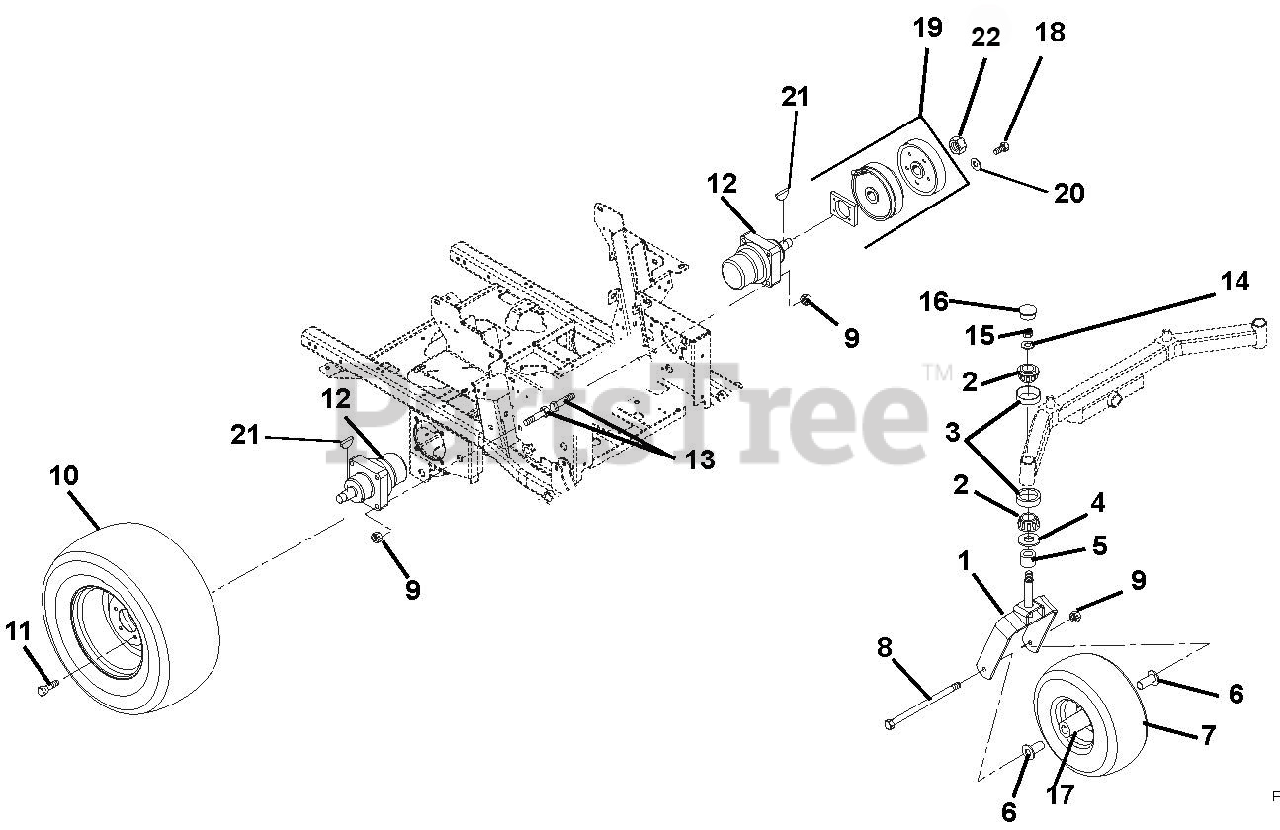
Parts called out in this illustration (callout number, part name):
1	FORK - FRONT
2	BRG, CONE W/ GREASE
3	BRG-CUP1.980X.420
4	BEARING SEAL 1.5 X 2 X .18
5	SPACER 1.005X1.5075X.375
6	SPACER, FRONT WHEEL
7	TIRE/WHEEL ASSY, 15X6.00-6
7	TIRE, 15X6.00-6
8	@BLT-HEX .50-13X9.00 GR5 YWZC
9	@NUT-LK-TOP-FLG .50-13 YWZC
10	TIRE/WHEEL ASSY, 24X11.50-12
10	TIRE, 24X11.50-12
10	TIRE/WHEEL ASSY, 23X10.00-12
10	TIRE, 23X10.00-12
11	BLT-LUG .50-20X1.38 YWZC
12	WHEEL MOTOR, 18E (CCW)
12	MOTOR, WHEEL HGM 15E (CCW)
13	BLT-HEX .50-13X2.75 YZ GR8
14	@WSHR-FL-STL.812X1.50X.135YWZC
15	NUT-JAM CTRLK .75-16 YWZC
16	CAP, DUST
17	BRG, 25MM ID X 52MM OD X 15MM
18	BLT-HEX .31-18X1.50 GR8YZ EP30
19	KIT, BRAKE SERVICE (1-SIDE)
20	@WSHR-LK .31X.078 REG YWZC
21	KEY-WDRF .31X1.00 SFT #B
22	HG HEX NUT 1-20 SLOTED
